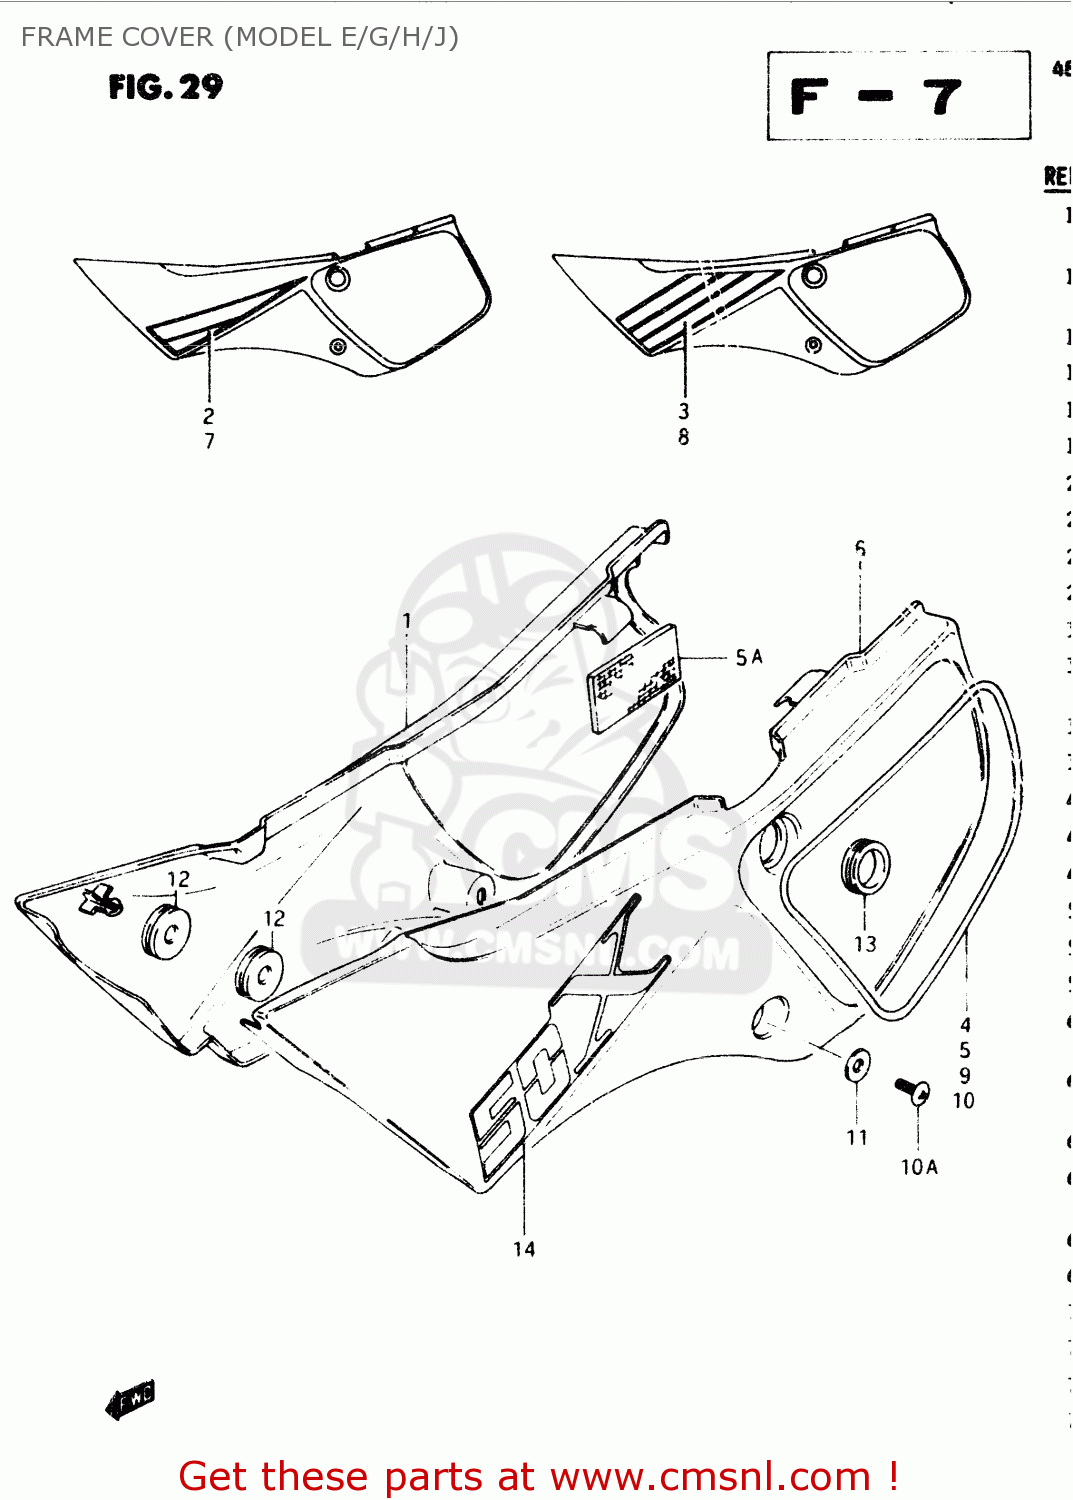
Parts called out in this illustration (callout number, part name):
1	COVER,FRAME RH
2	TAPE SET, FRAME COVER RH
3	TAPE SET, FRAME COVER RH
4	TAPE, FRAME COVER RH (BLUE)
5	TAPE, FRAME COVER RH (BLUE)
5A	HEAT SHIELD,FRAME COVER
6	COVER,FRAME LH
7	TAPE SET, FRAME COVER LH
8	TAPE SET, FRAME COVER LH
9	TAPE, FRAME COVER LH (BLUE)
10	TAPE, FRAME COVER LH (BLUE)
10A	SCREW 6X12
11	WASHER
12	CUSHION
13	GROMMET,SEAT LOCK HOLE
14	EMBLEM, FRAME COVER
